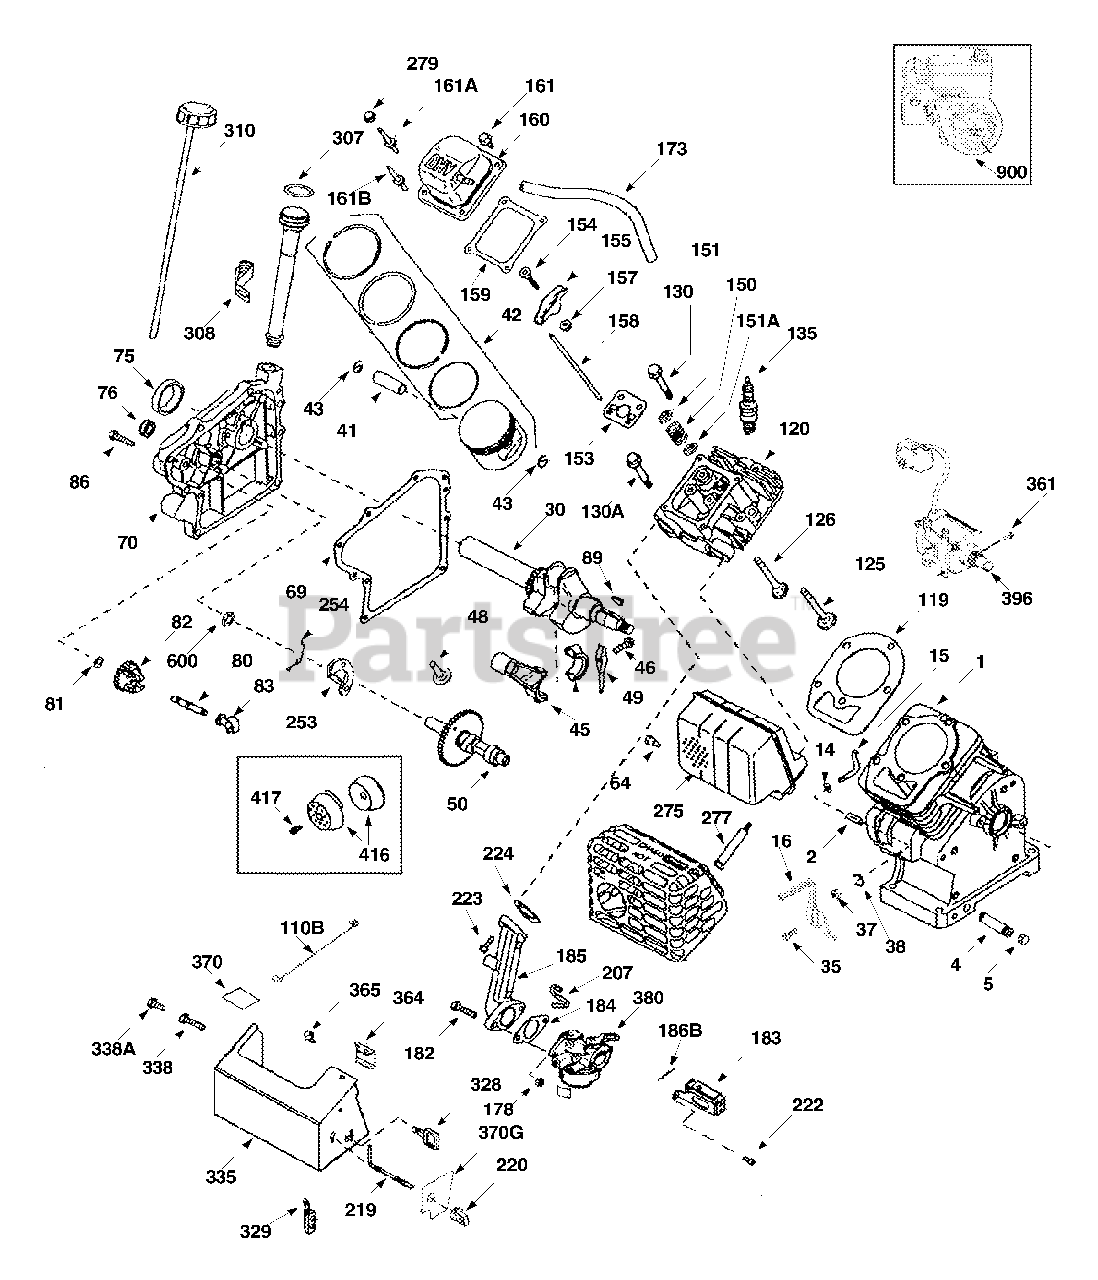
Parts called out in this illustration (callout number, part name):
1	Cylinder
2	Dowel Pin
4	Oil Drain Extension
5	Extension Cap
15	Governor Rod
16	Governor Lever
30	Crankshaft
35	Screw, 10-32 x 63/64"
37	Lock Nut, 10-32
38	Retaining Ring
41	Piston & Pin Ass'y (Std.)
41	Piston & Pin Ass'y (.010" OS)
42	Ring Set (Std.)
42	Ring Set (.010" OS)
43	Piston Pin Retaining Ring
45	Connecting Rod Ass'y
46	Connecting Rod Bolt
48	Valve Lifter
49	Oil Dipper
50	Camshaft
64	Screw, 1/4-20 x 27/32"
69	Cylinder Cover Gasket
70	Cylinder Cover
75	Oil Seal
76	Camshaft Seal
80	Governor Shaft
82	Governor Gear Ass'y
83	Governor Spool
86	Screw, 1/4-20 x 1-1/4"
89	Flywheel Key
110B	Ground Wire
119	Cylinder Head Gasket
120	Cylinder Head
125	Exhaust Valve (Std.)
125	Exhaust Valve (1/32" OS)
126	Intake Valve (Std.)
130	Screw, 5/16-18 x 1-1/2"
130A	Screw, 5/16-18 x 2-41/64"
135	Resistor Spark Plug (RN4C)
150	Valve Spring
151	Valve Spring Cap
151A	Intake Valve Seal
153	Push Rod Guide
154	Rocker Arm Stud
155	Rocker Arm
157	Nut, 1/4-28
158	Push Rod
159	Rocker Arm Cover Gasket
160	Rocker Arm Cover
161	Screw, 1/4-20 x 31/64"
173	Breather Tube
178	Nut, 1/4-20
182	Screw, 1/4-20 x 1"
183	Choke Bracket
184	Carburetor To Intake Pipe Gasket
185	Intake Pipe
186B	Choke Spring
207	Throttle Link
219	Choke Rod
220	Choke Knob
222	Screw, 10-32 x 1/2"
223	Screw, 1/4-20 x 1"
224	Intake Pipe Gasket
253	Compression Release Weight
254	Compression Release Spring
275	Muffler
277	Screw, 1/4-20 x 2-9/32"
279	Nut & Lock Washer
308	Fill Tube Clip
310	Dipstick
328	Ignition Key
329	Terminal
335	Carburetor Cover
338	Screw, 10-32 x 1/2"
338A	Screw, 10-32 x 3/8"
361	Screw, T-30, 1/4-20 x 15/32"
364	Carburetor Cover Bracket
365	Screw, 10-32 x 1/2"
370G	Instruction Decal
380	Carburetor
396	Electric Starter Motor
416	Spark Arrestor Kit
417	Screw, 10-32 x 1/2"
900	Shortblock
